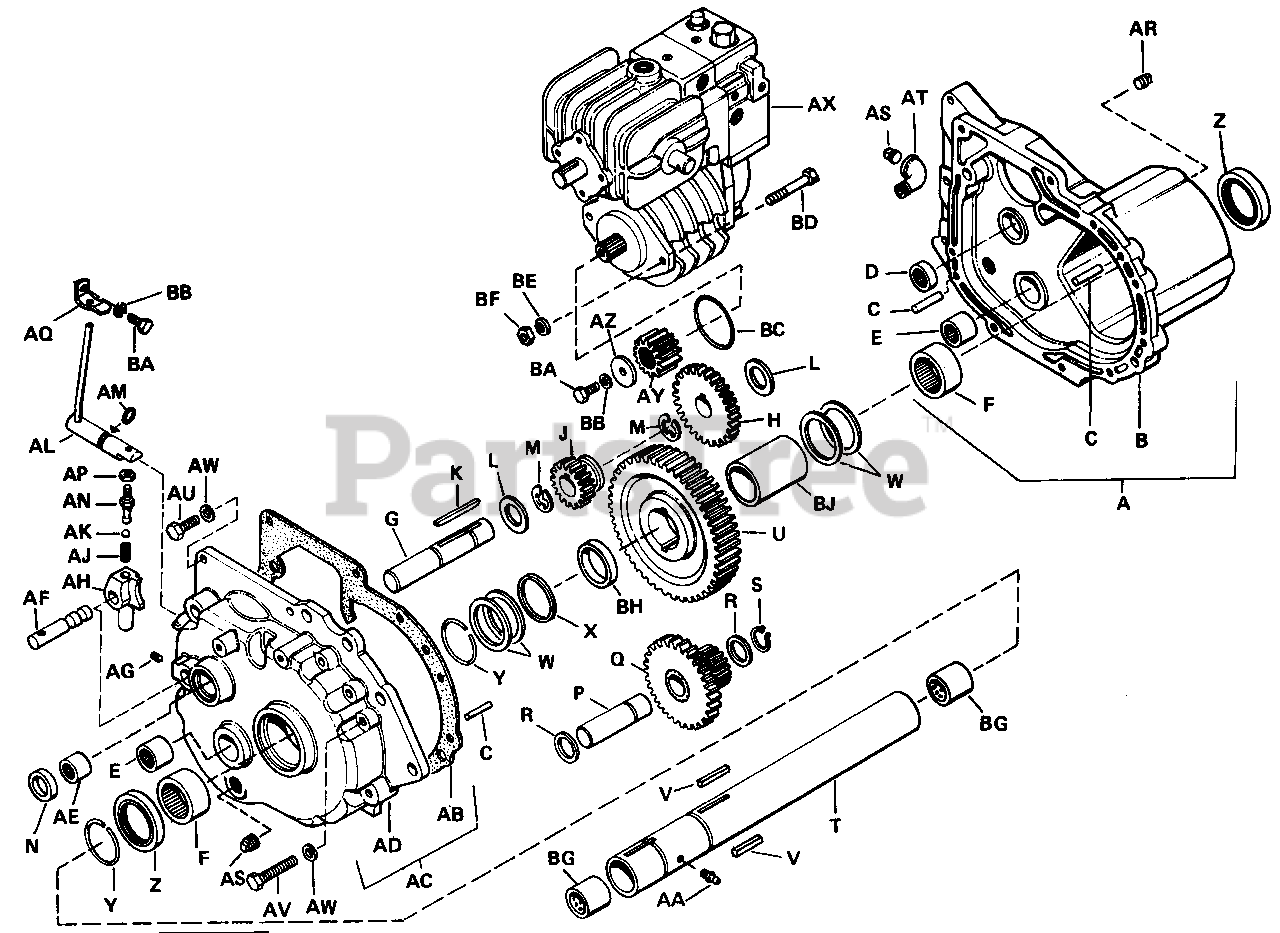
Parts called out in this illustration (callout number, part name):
A	Gear Case Complete (includes B thru F)
B	Gear Case
C	Roll Pin, 3/8" x 1-1/4"
D	Needle Bearing
E	Needle Bearing
F	Needle Bearing
G	Brake Shaft
H	Gear-1st Interm.
J	Sliding Pinion
M	Retainer Ring
P	Shaft, Interm.
Q	Pinion & Gear Assembly
S	Retaining Ring
T	Axle Tube Assembly
U	Drive Gear
AA	Grease Fitting
AB	Gear Case Gasket
AC	Gear Case Cover Sub. Assy. (includes AD, AE, E, F)
AD	Gear Case Cover
AE	Needle Bearing
AF	Shifter Shaft
AG	Cone Pt Setscrew, Hollow Hd., 5/16"-18 x 1/2"
AH	Shift Fork
AK	Shift Lock Ball
AL	Shift. Shaft Assembly
AP	Hex. Jam Nut, 5/16"-24
AQ	Lift Lever Latch
AR	Pipe Plug, 1/4"
AS	Pipe Plug, 3/8"
AT	Street Elbow, 3/8" x 90ø
AU	Hex. Capscrew, 5/16-18 x 1"
AV	Hex. Capscrew, 5/16-18 x 2"
AW	Lock Washer, 5/16"
AX	Hydrostatic Pump & Motor Unit
AY	Motor Shaft Pinion
BA	Hex. Capscrew, 5/16-24 x 5/8"
BB	Lock Washer, 5/16"
BD	Hex. Capscrew, 7/17-14 x 4"
BE	Lock Washer, 7/16"
BF	Hex. Nut, Full, 7/16"-14
BH	Spacer (R.H.Side)
BJ	Spacer (L.H.Side)
